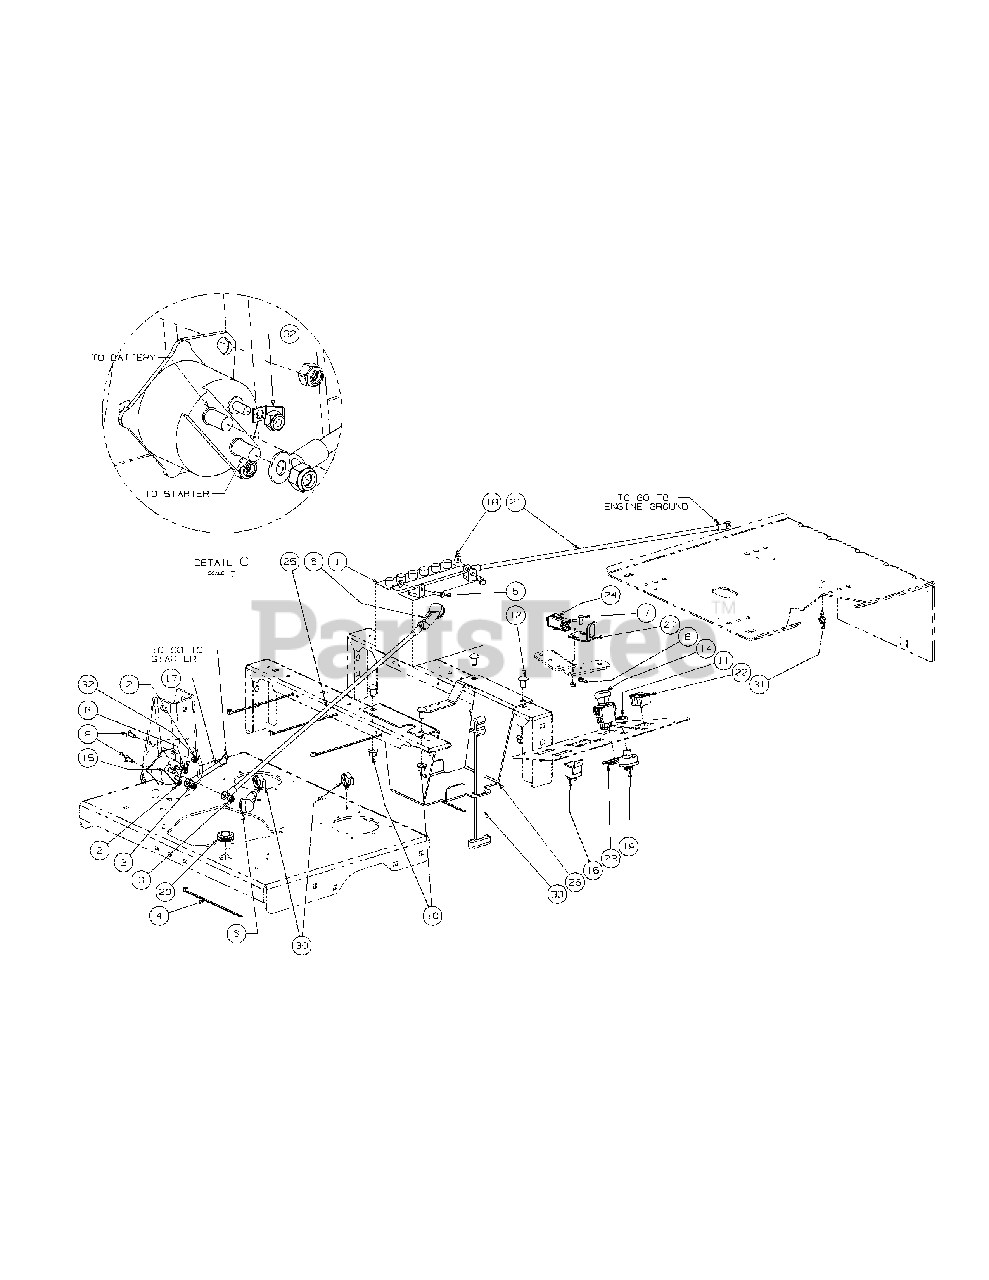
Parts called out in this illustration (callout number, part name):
1	Battery, 12V 225CCA 30 Min
2	Lock Nut w/Nylon Insert
3	Nylock Nut, 5/16-18
4	Tie, Cable, 3/16 x .05 x 7.4"
5	Screw, Hex, Cap, 1/4-20 x .75
6	Boot, 1" OD Rubber Battery-PST, Red
7	Round Hd. Machine Screw, 10-32 x 3/4
8	Nut, Lock, Nylon Insert, #10-32
9	Carriage Bolt, 1/4-20 x .750
10	Hex Nut, Flange Lock, 3/8-16
11	Nut, W/Cap, 5/8-32 Ignition
12	Carriage Bolt, 3/8-16 x .75 Long
13	Hourmeter, Harness
14	Switch, Electric, PTO
15	Solenoid Magnetic Switch
16	Relay, 12V 40A
17	Cable, Battery Red, 5"
18	Hex Flange Lock Nut, 1/4-20
19	Switch, Ignition, 6 Pin
20	Grommet, .75 ID
21	Cable, Battery Black, 28"
22	Meter, Hour
23	Bracket, PTO Switch Retainer
24	Switch, Safety N.O./N.C.
25	Cable, Battery Red, 42"
26	Battery Bracket
27	Control/Brake Panel Switch
28	Wire Harness Adaptor
29	Harness Assembly
30	Electrical Conduit Clip, 5/8
31	Electrical Conduit Clip, 3/8
32	Terminal Tab, 1/4" Blade
33	Strap, Battery
